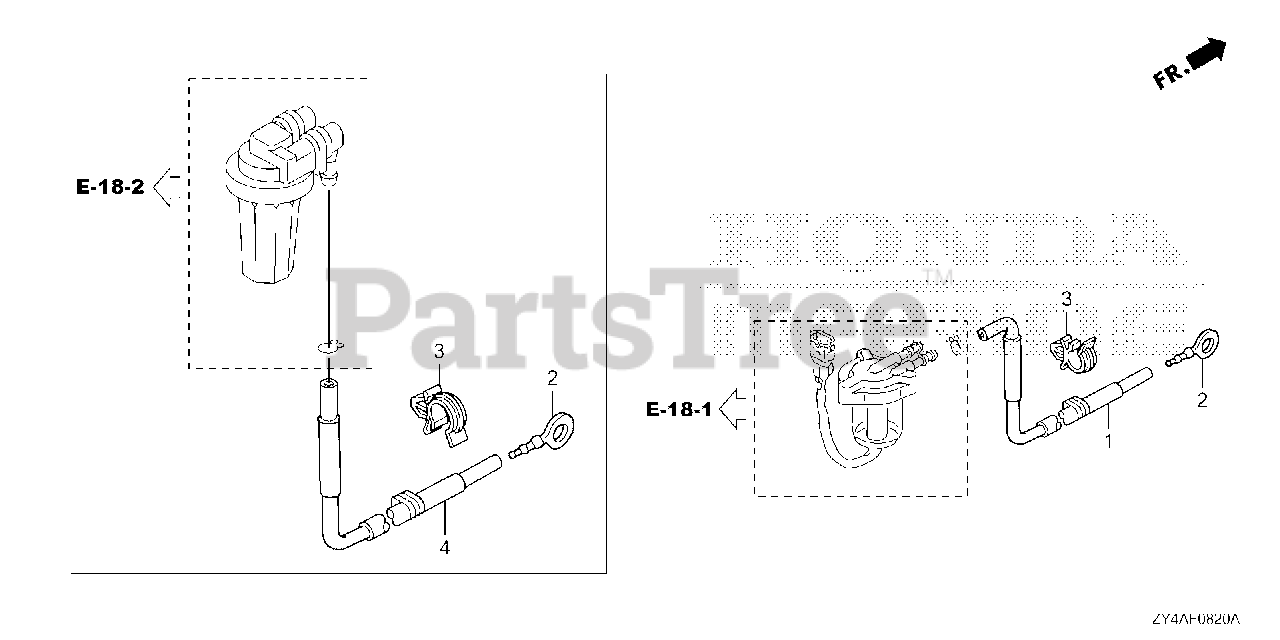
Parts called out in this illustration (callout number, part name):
2	PLUG, FUEL TUBE
3	HOLDER, ROD (A)
4	TUBE A, FUEL
